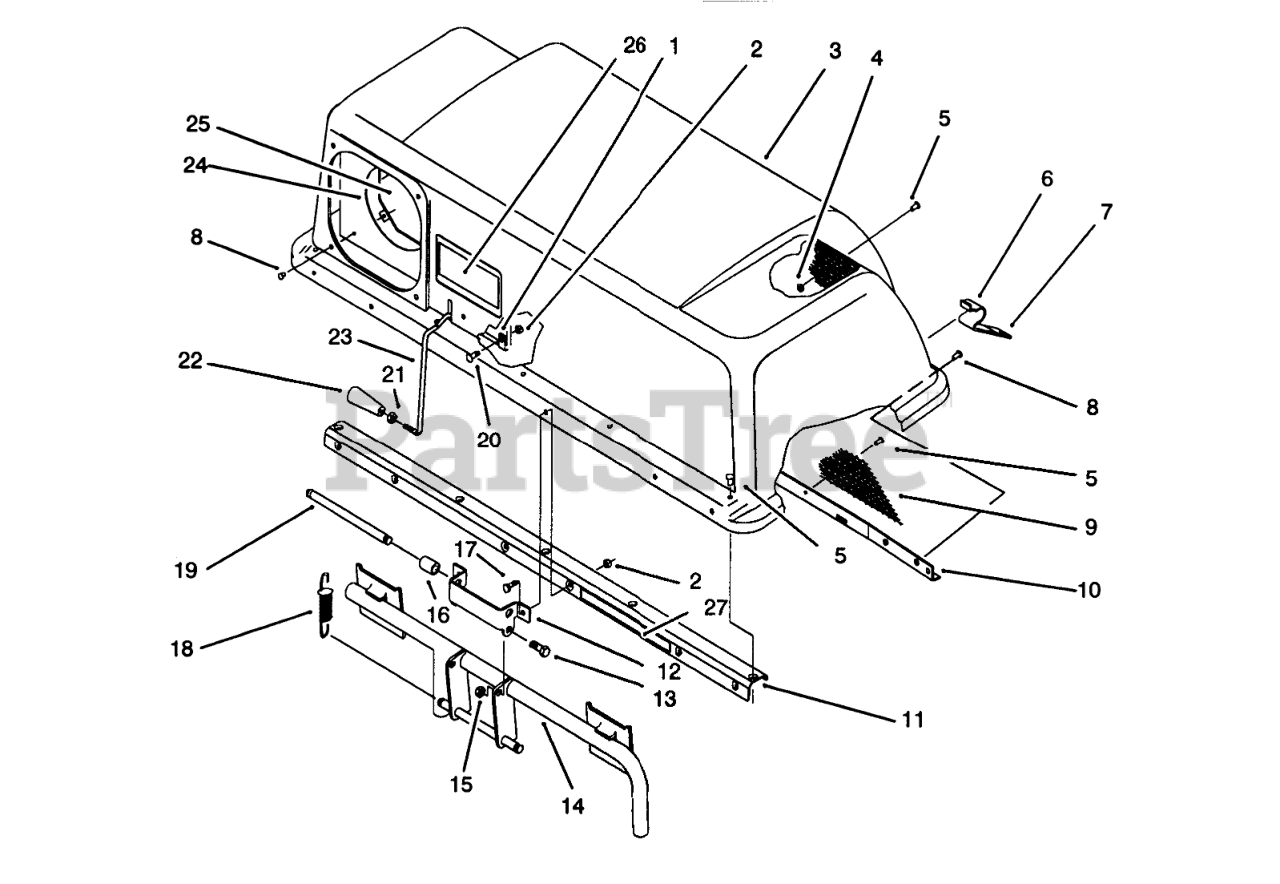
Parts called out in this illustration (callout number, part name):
1	Clip
2	NUT-LOCK, NI
3	TOP-BAGGER
4	Washer
5	RIVET-BLIND
6	Latch-Bag
8	Pop Rivet
9	SCREEN-BAGGER
10	Screen Support
11	Stiffener Assembly (Incl Ref. #27)
12	HINGE-BAG TOPB
13	SCREW-HH
14	FRAME ASM
15	NUT-LOCK, NI
16	SPACER
17	SCREW-HH
18	SPRING-EXTENSION
19	PIN-SPRING
20	Screw
21	NUT-JAM
22	HANDLE-TAPERED
23	FEELER-FILL, BAG
24	SEAL-CHUTE
25	CLAMP-SEAL
26	DECAL
27	Decal
